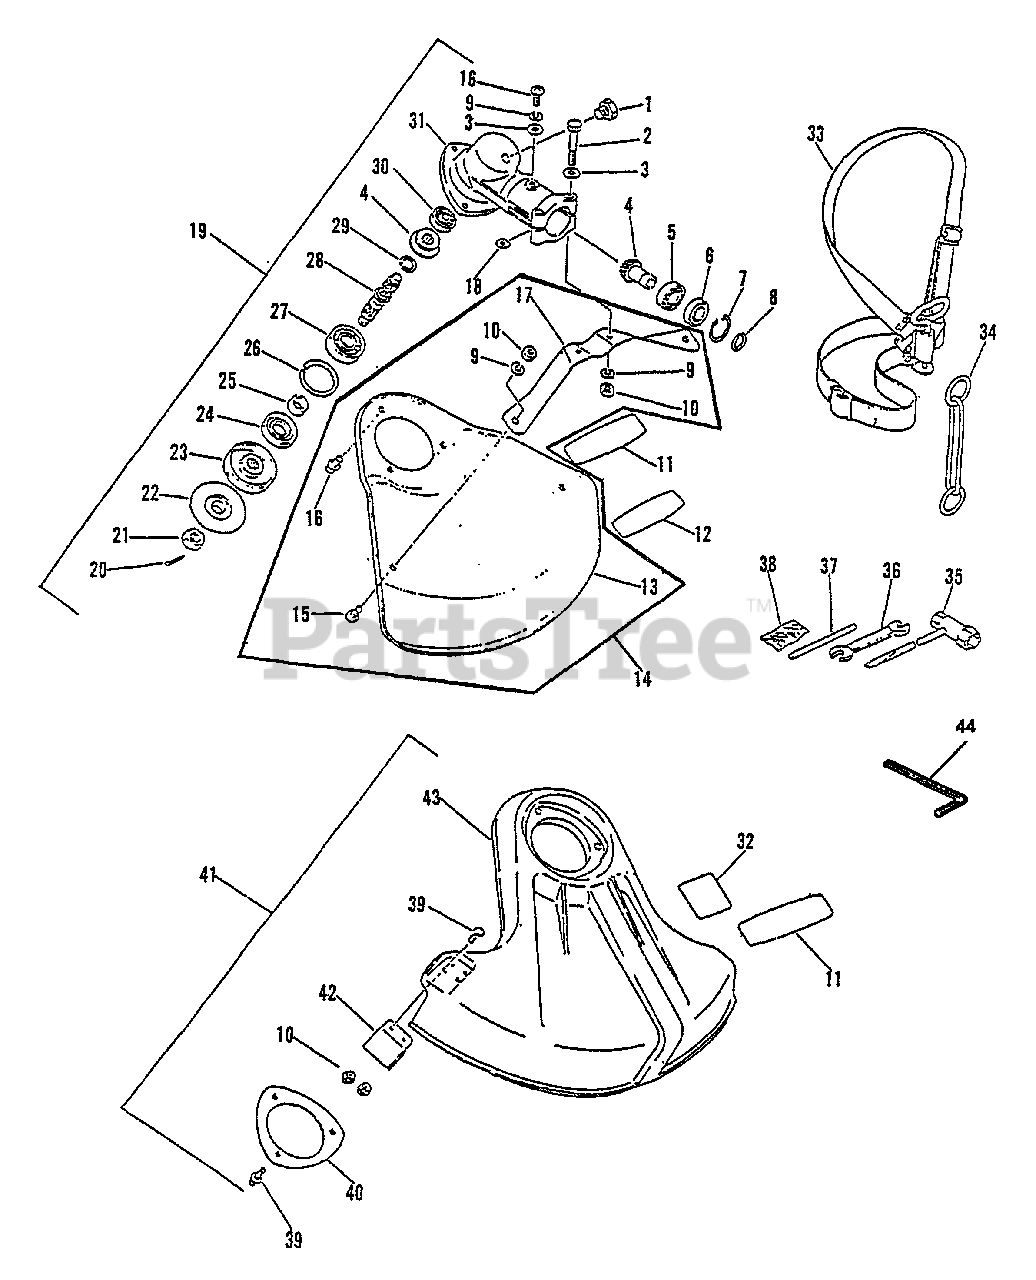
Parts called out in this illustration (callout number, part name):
1	BOLT 8×8 SP
2	BOLT 5×35 SP
3	WASHER, FLAT 5.5×10×0.8
4	GEAR SET
5	BEARING, BALL 6900
6	BEARING, BALL 6900Z
7	RING, SNAP Ø22
8	RING, SNAP Ø12
9	WASHER, SPRING 5
10	NUT M5
11	LABEL
12	LABEL - CAUTION
13	SHIELD, METAL DEBRIS
14	SHIELD ASSY
15	SCREW 5×8
16	SCREW 5×10
17	BRACKET, SHIELD MOUNTING
19	GEAR CASE ASSY
20	PIN, COTTER 2×22
22	PLATE, ADAPTOR - LOWER
23	PLATE, ADAPTER - UPPER
24	SEAL, OIL 22
25	SPACER 11.8×15×9
26	RING, SNAP Ø32
27	BEARING, BALL - 6201 C3
28	SHAFT, GEAR
29	RING, SNAP Ø10
30	BEARING, BALL 609
31	HOUSING, GEAR CASE
32	LABEL, CAUTION
33	SHOULDER STRAP ASSY
34	HOOK
35	T-WRENCH 17x-19 L200
36	SPANNER 8×10
37	TOOL, LOCKING 5×120 MM
38	PIN, COTTER 2×22 (PKG. OF 10)
39	SCREW 5×16
40	PLATE, SHIELD Ø49.5 MM
41	DEBRIS SHIELD ASSY
42	CUTTER, LINE
43	SHIELD, DEBRIS
44	WRENCH, ALLEN 3 MM
